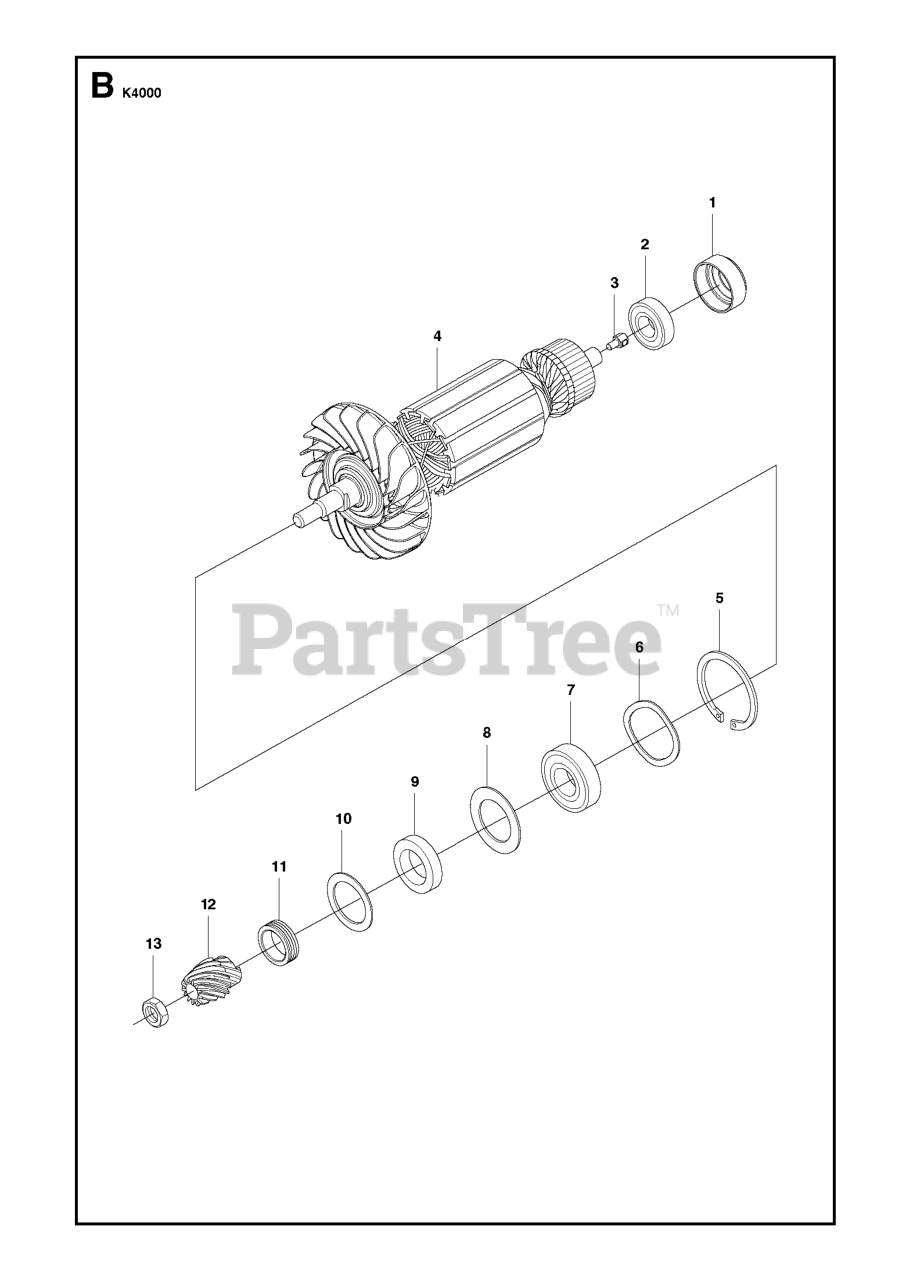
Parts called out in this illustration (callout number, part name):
1	RUBBER BUSHING ROTOR CENTRERIN
2	BALL BEARING
3	SCREW MAGNET
5	RETAINING RING SGH 35
6	SPRING WASHER
7	BALL BEARING
9	FELT JOINT
13	NUT K3000 M8X1 LEFT
